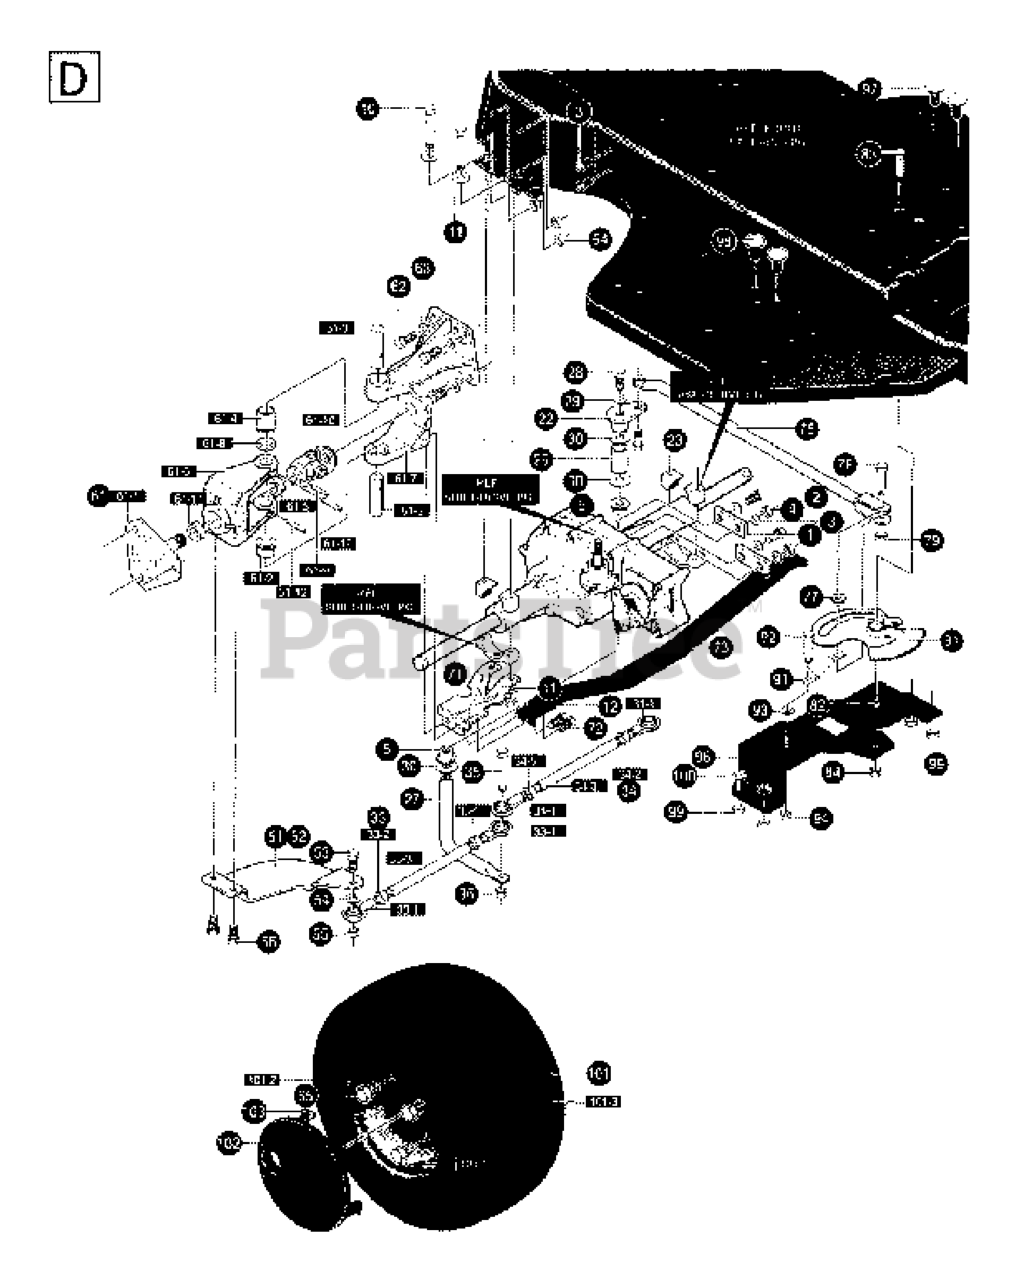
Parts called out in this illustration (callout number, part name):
2	BRACKET NLA
4	SCREW
6	Bolt Fin Hex 5/16 - 18 Unc x 2 Gr. 2
7	WASHER
10	WASHER
11	NUT
17	BOLT.HEX.1/4.X.3/4.DICHROMATE
18	NUT.CROWNLOCK.1/4
33	BOLT.HEX.1/4.X.3/4.DICHROMATE
34	NUT
36	NUT
49	NUT
64	WASHER - 25X8.5X2.3
66	LOCK WASHER
68	BOLT.HEX.1/4.X.3/4.DICHROMATE
97	SCREW
98	NUT
115	NUT
127	NUT
133	BRACKET NLA
134	SCREW
143	WASHER
153	NUT
154	WASHER
162	RETAINER,STROP BELT
163	BOLT 3/8ä-16X1,5ä
164	NUT
165	WASHER 3/8ä
